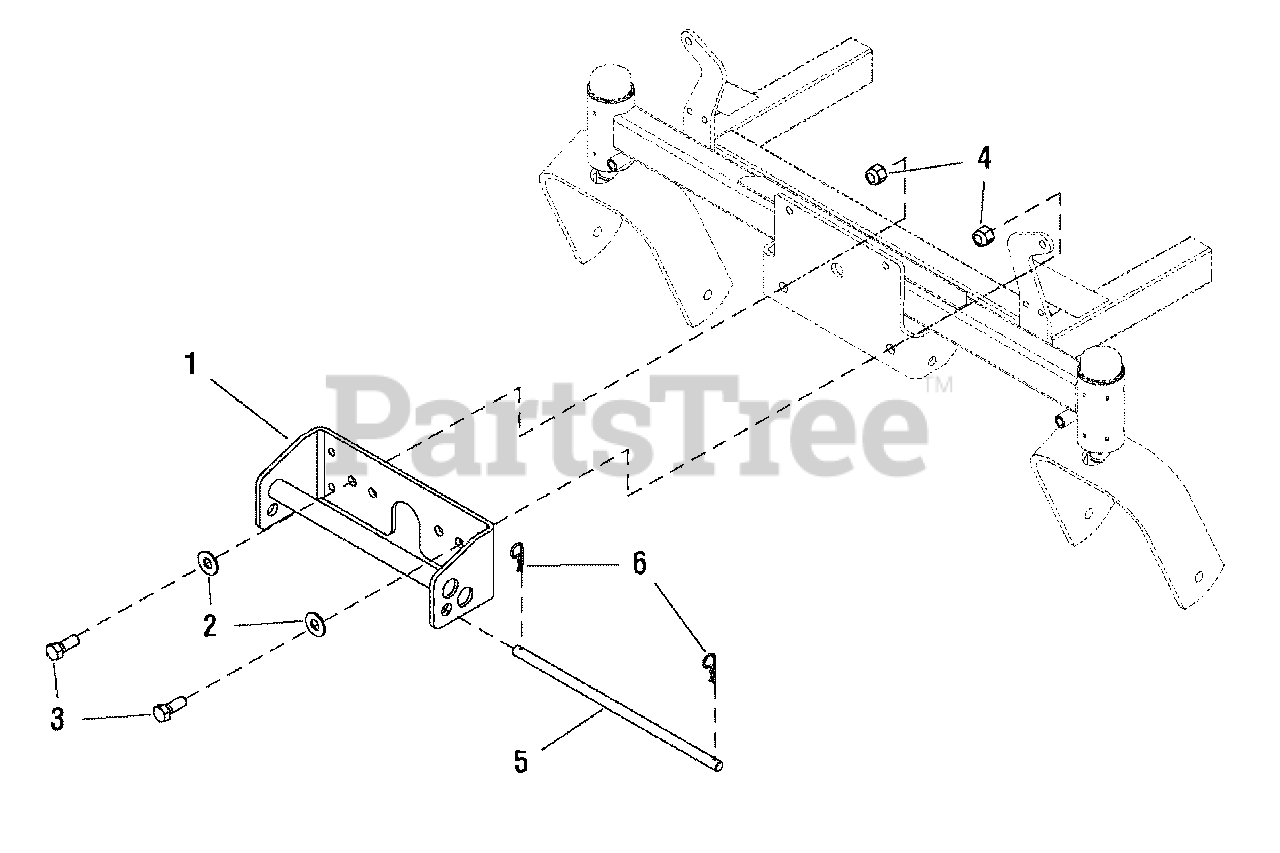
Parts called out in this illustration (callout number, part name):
1	HOLDER ASSEMBLY, Weight
2	NUT, Hex Nylock Flange, 1/2 - 13
2	NUT, Hex Nylock Flange, 3/8 - 16
3	CAPSCREW, Hex Head, 1/2 - 13 x 1-1/4
3	CAPSCREW, Hex Head, 3/8 - 16 x 1-1/4
4	WASHER, 1/2
4	WASHER, 3/8
5	ROD, Bagger System
6	PIN, Quick
